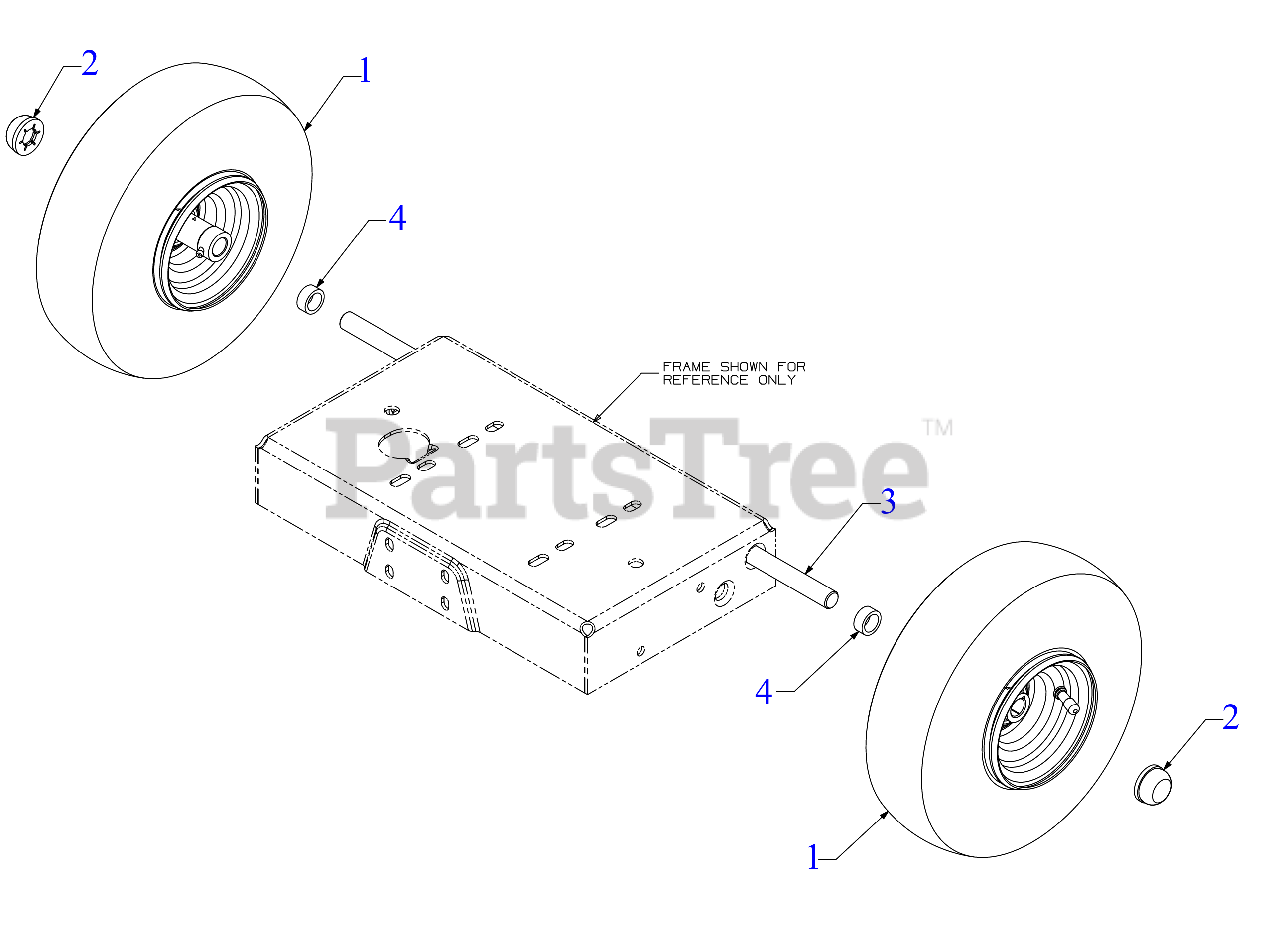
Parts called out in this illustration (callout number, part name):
1	TIRE & RIM (10x4x4) (CRAFTSMAN GRAY)
2	PUSH CAP
3	SHREDDER AXLE
4	SPACER
